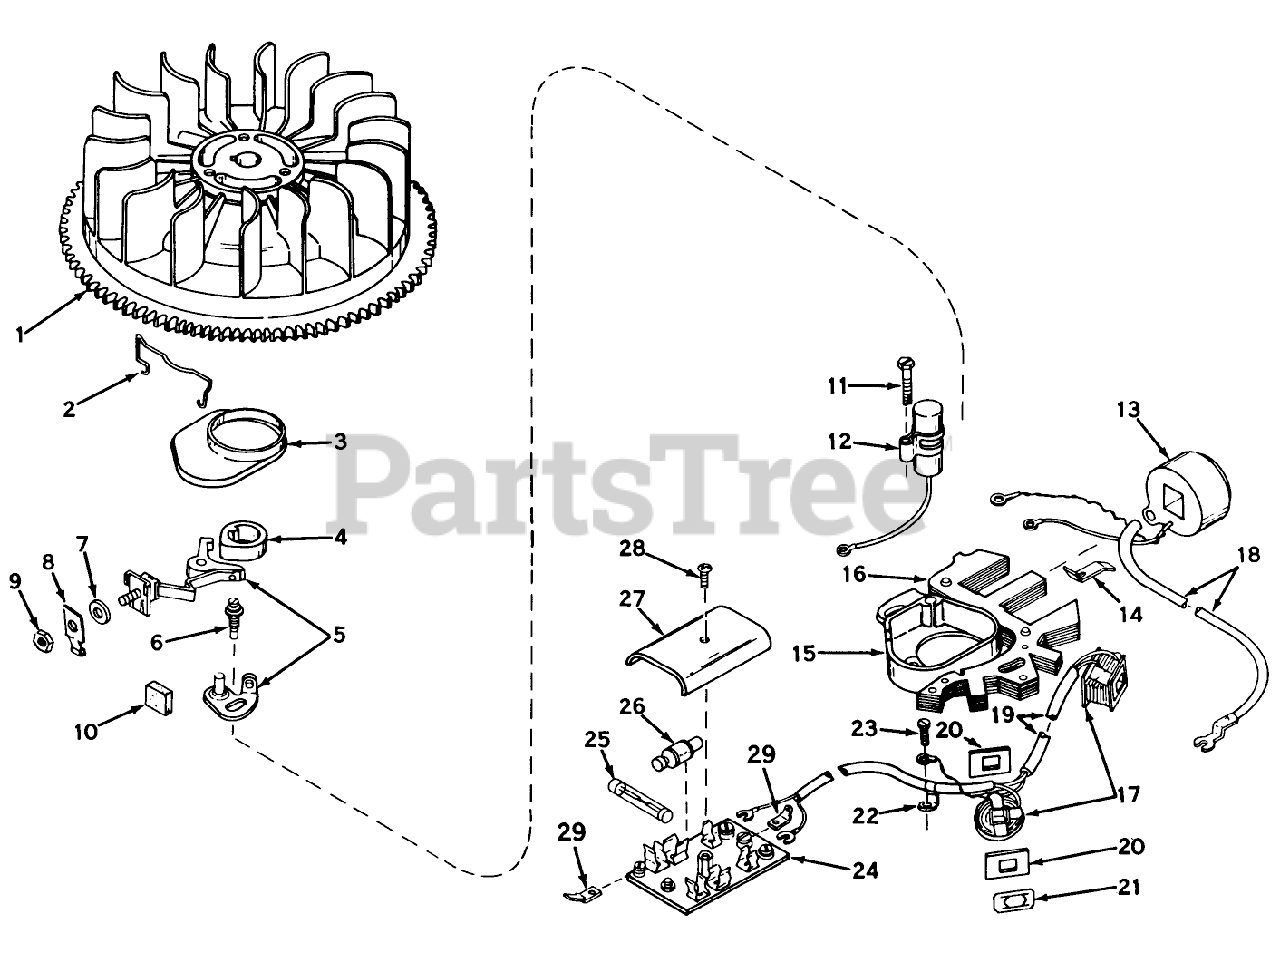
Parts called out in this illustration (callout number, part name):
1	Flywheel
2	Spring, Dust cover
3	Cover, Dust
4	Cam-Breaker
5	Breaker Assv.
6	Breaker Screw
7	Washer
8	Terminal
9	DECAL
10	Felt,Cam Wiper
11	Condenser Screw
12	Condenser
13	Coil Assy., (Inc. Ref. Nos. 12, 13 18)
14	Spring Coil Wedge
15	Stator Plate Assy. (Incl. Nos. 2, 3, 5 thru 28)
16	DECK ASM
17	Generator Coils Leads
18	Wire, Lead
19	Sleeve, Insulation
20	Shield, Coil
21	Clip, Coil fastening
22	Clip, Ground
23	Screw, Ground
24	Plate, Rectifier (Does not incl. 25 26)
25	Fuse
26	Rectifier
27	Cover, Panel
28	Screw
29	Terminal
